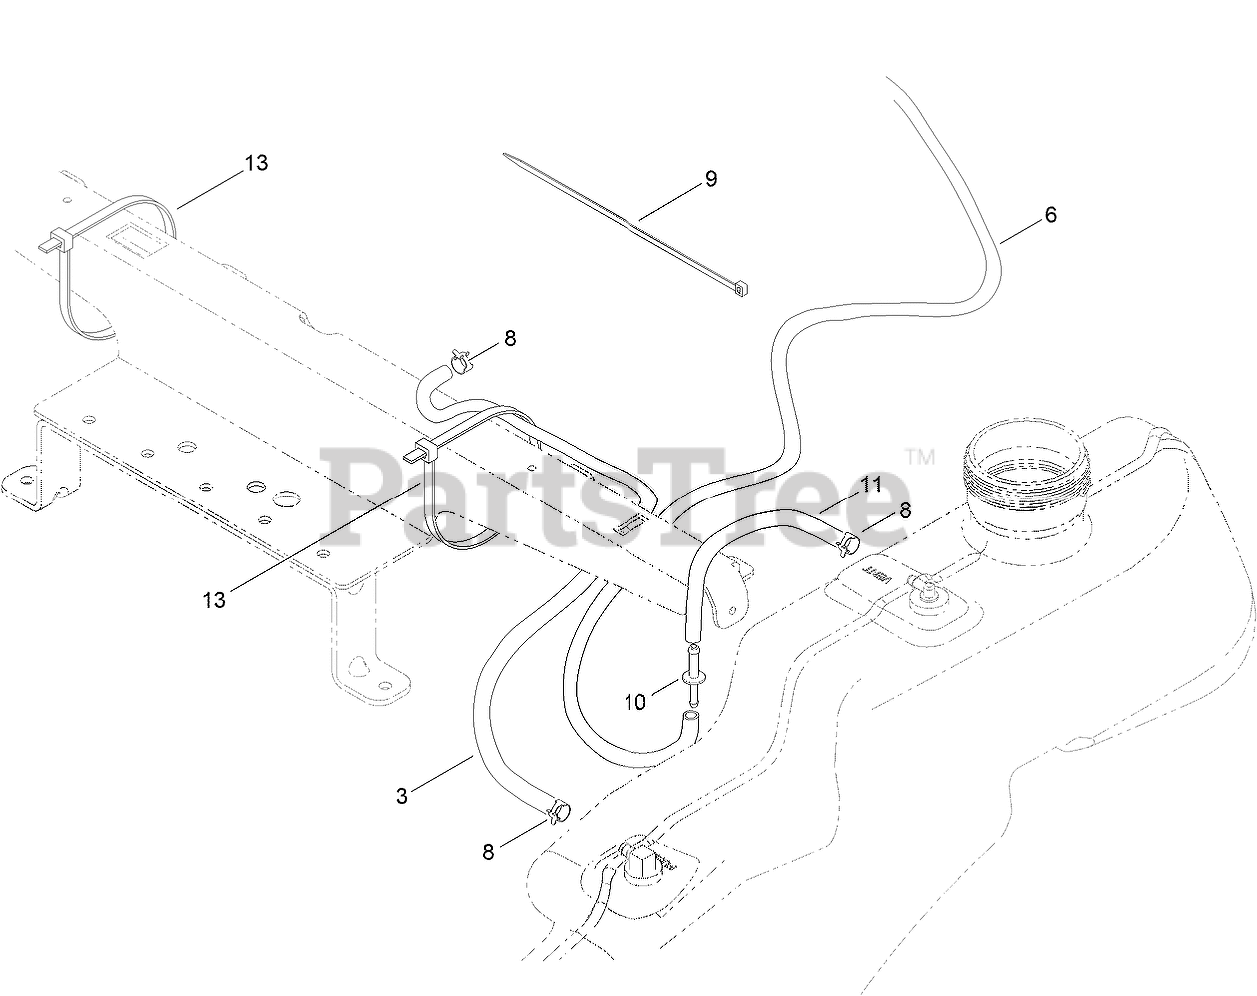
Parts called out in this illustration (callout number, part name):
3	HOSE-FUEL
6	HOSE-FUEL
8	CLAMP-HOSE
9	TIE-CABLE
10	ADAPTOR-ORIFICE
11	HOSE-FUEL
13	TIE-CABLE
